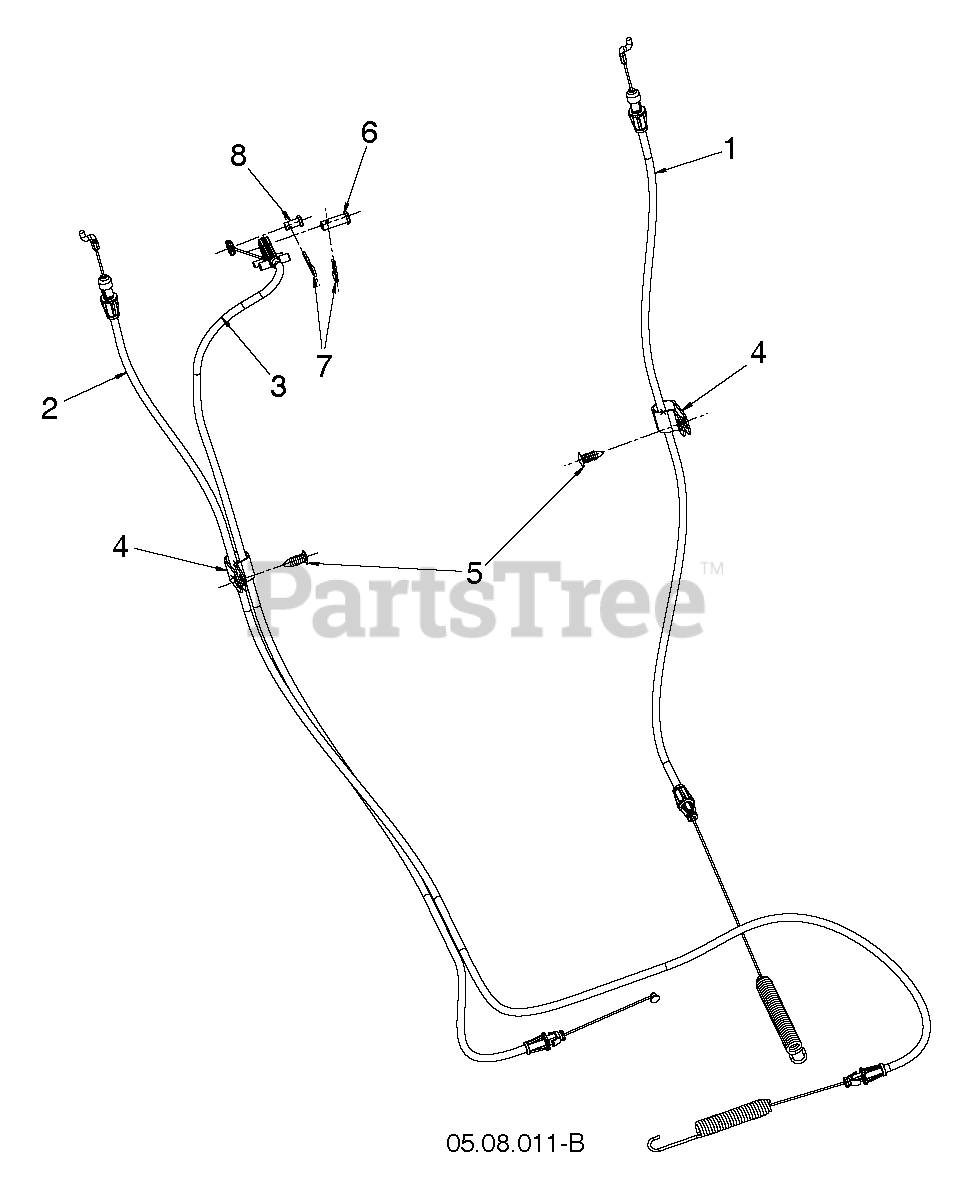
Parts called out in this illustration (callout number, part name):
1	Drive Control Cable, 16
2	Auger Control Cable
3	Speed Control Cable, DSST OPP
4	CLIP.CABLE.BLK
5	FASTENER.PUSH.O.250X0.783
6	Clevis Pin, 5/16 X .875
8	Clevis Pin, .25 X .31
